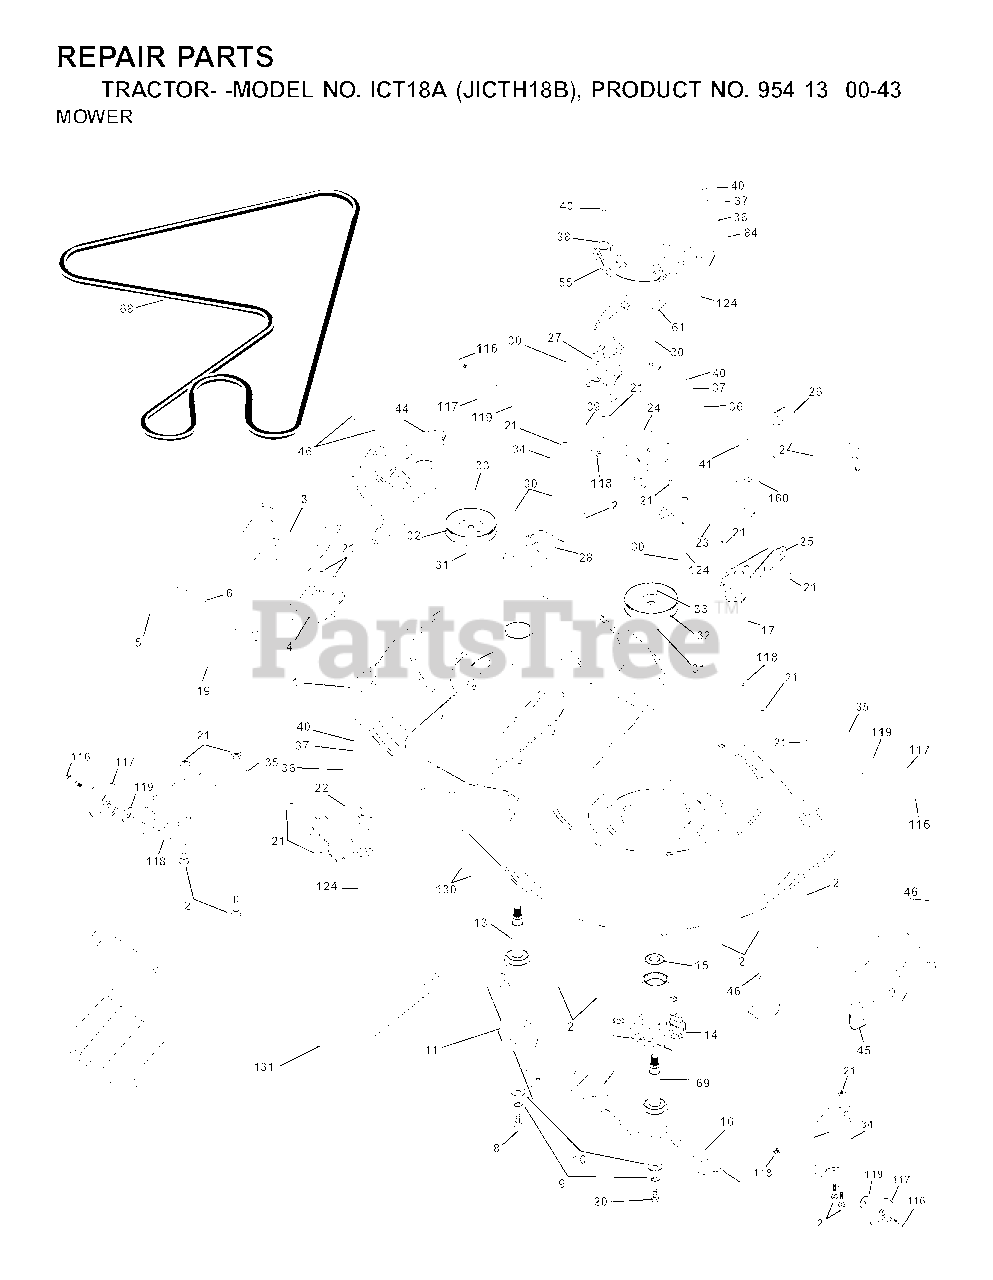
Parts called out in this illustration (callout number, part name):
2	BOLT
3	BRACKET
5	RETAINER-SPRNG RB
6	BAR SWAY
8	BLADE BOLT
9	LOCKWASHER
10	WASHER.BLADE
11	BLADE, LH (CTH150)
13	SHAFT ASM VENT
14	HSG MANDREL
16	RP BLADE RH (CTH150)
17	BOLT.3/8-14X1.25
19	BOLT SHD 5/16-18
21	LOCKNUT
22	BRACKET
23	BRACKET
26	BRACE
27	BRACKET
30	SCREW THDROL ROLLING WASHER HD
31	WASHER
33	NUT
34	BRACKET
36	PULLEY.IDLER.4.25
40	LOCKNUT
41	NUT LOCK FLG 3/8-16 UNC
45	MANDREL COVER RH
46	SCREW.1/4-20X5/8
55	ARM IDLER
68	HEX-BELT 107 MOWER
69	SHAFT.ASM.W/LWR.BRG.RH.THREAD
84	KEEPER, BELT IDLER
116	BOLT, SHOULDER
117	WHEEL GAGE DONUT
118	LOCKNUT
119	WASHER
124	BOLT.3/8-16X1.50
131	CHUTE BAGGER
